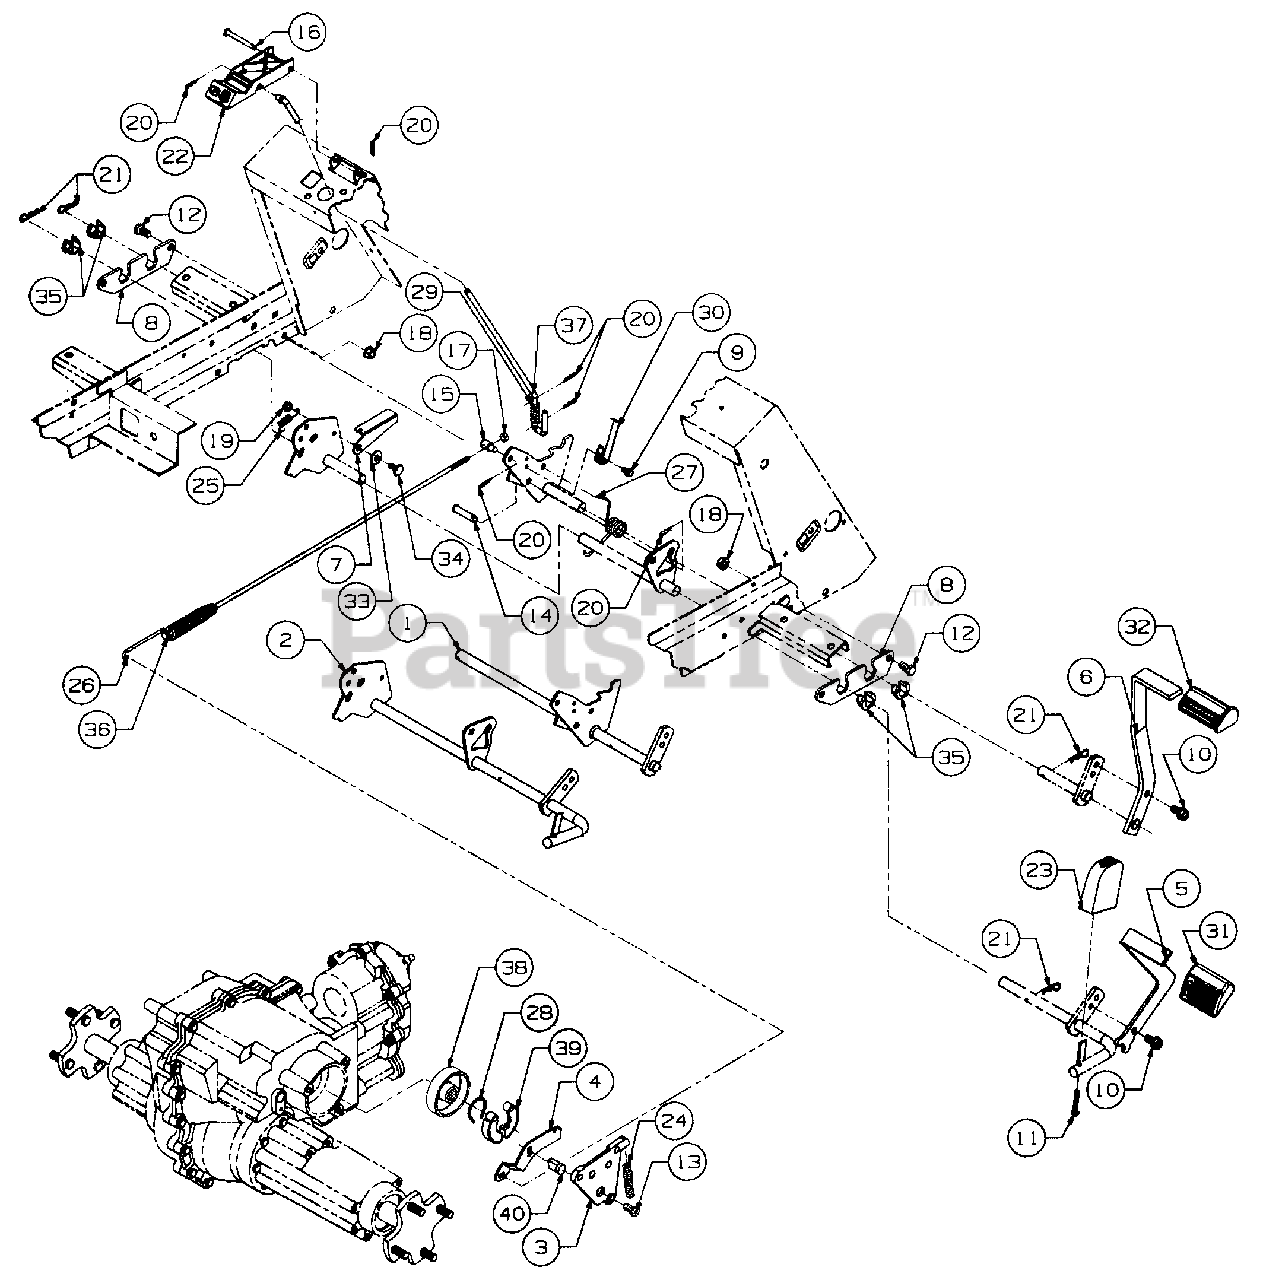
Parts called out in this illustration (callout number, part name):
1	Shaft Assy, Brake
2	Shaft Assy, Forward/Reverse
3	Plate, Brake
4	Arm, Brake
5	Pedal, Forward
6	Pedal, Brake
7	Actuator, Reverse Switch
8	Plate, Bearing Mounting
9	Screw, Hex Wash Tapp, 1/4 x .50 Lg
10	Screw, Hex Wash Tap, 3/8-16 x .75 Lg
11	Screw, Truss Mach Tapp, #12 x 1.5
12	Screw, Hex Cap, 3/8-16 x .75 GR5
13	Screw, Low Hd Cap, 3/8-16 x .75
14	Pin, Clevis, 3/8 OD x 1.62 Lg
15	Ferrule, Adjustment
16	Pin, Clevis, 1/4 OD x 2.38 Lg
17	Nut, Hex Sems, 1/4-20
18	Nut, Hex Flanged Lock, 3/8-16
19	Nut, Hex Flange Lock, 1/4-20
20	Pin, Internal Cotter, 5/16 Dia x 1.12
21	Pin, Internal Cotter, 3/8 Dia x 1.625
22	Lever, Park Brake
23	Pad, Reverse Pedal
24	Spring, Compression
25	Spring, Extension, .38 OD x 2.10 Lg
26	Spring, Extension, .75 OD x 5.0 Lg
27	Spring, Torsion
28	Spring, Brake
29	Spring, Compression, .5 OD x 2.23
30	Actuator, Neutral Switch
31	Pad, Forward Pedal
32	Pad, Brake Pedal
33	Washer, Flat, .406 x .75 x .063
34	Bolt, Shoulder, .375 Dia x .181 Lg
35	Bearing, Hex Flange Split
36	Rod, Brake
37	Rod, Park Brake Engagement
38	Drum, Brake
39	Shoe, Brake
40	Actuator, Brake Shoe
